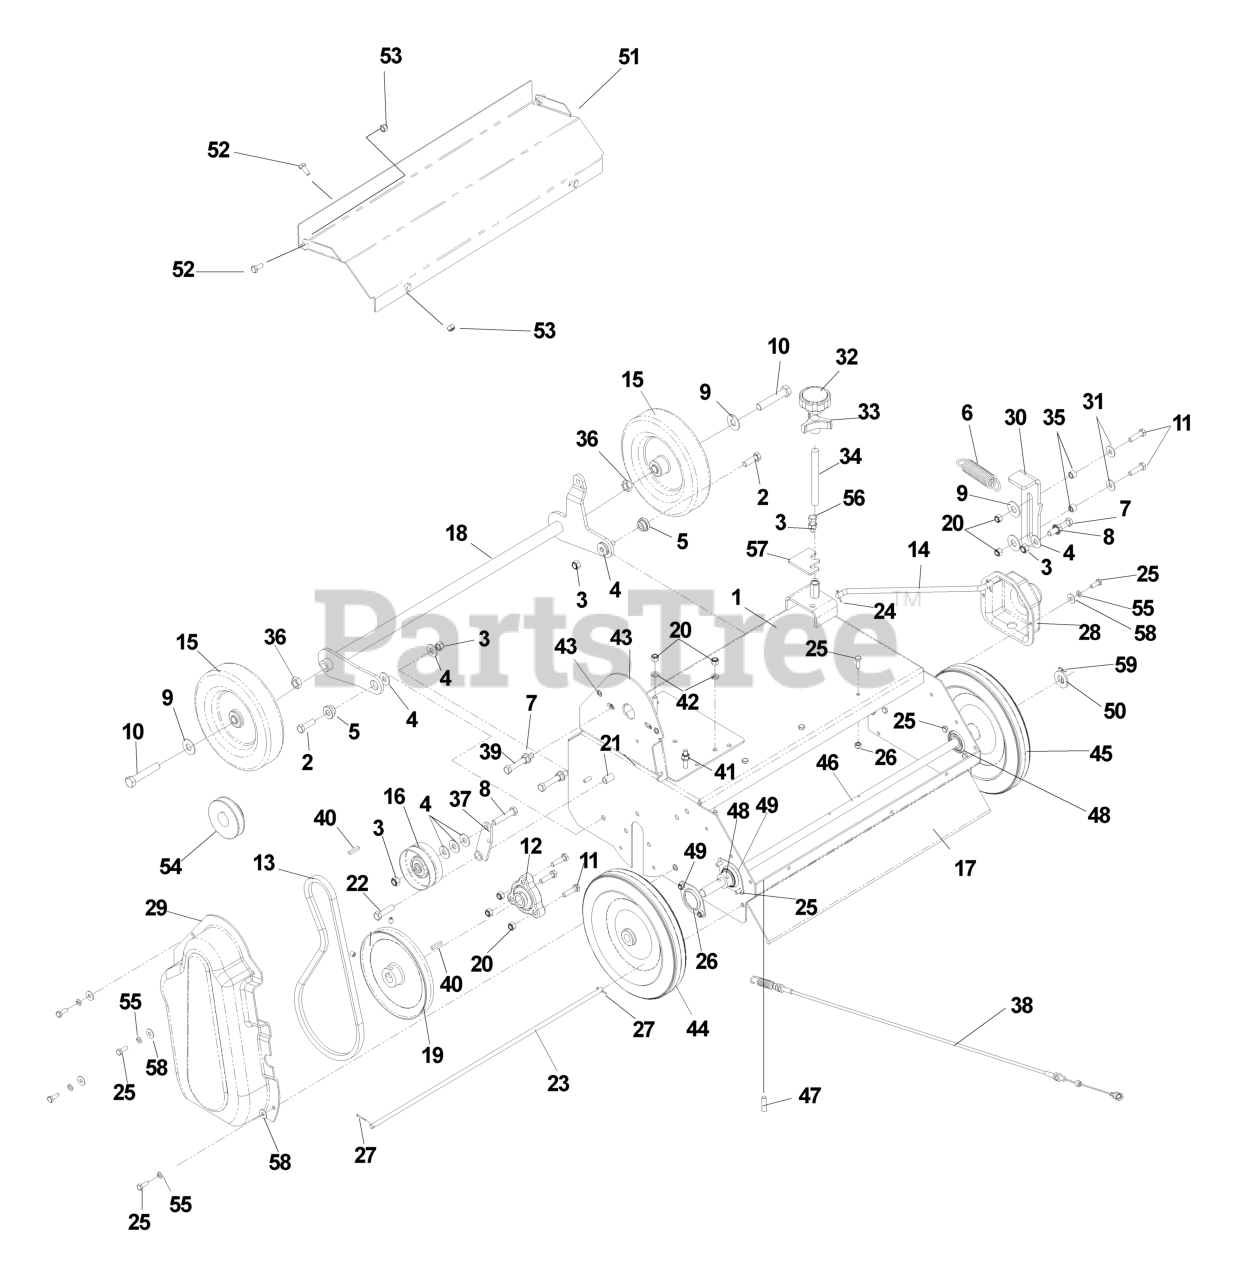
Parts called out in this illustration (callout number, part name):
1	BODY ASSEMBLY
2	HCS 3/8C X 1 1/4 GR5
3	NUT 3/8-16 NYLOC
4	WASHER 3/8 FLAT
5	BUSHING RAKE
7	NUT 3/8C WHIZ
8	HCS 3/8C X 2
9	WASHER 1/2 FLAT
10	HCS 1/2C X 2 3/4
11	HCS 5/16C X 1 1/4
12	BEARING, FLANGED
13	BELT, DRIVE RAKE/SLICER DFS
15	WHEEL 8 X 1 3/4 RAKE
16	PULLEY, IDLER RAKE & ZTR
18	FRONT AXLE
19	PULLEY W/SET SCREW
20	NUT 5/16 NYLOC
21	BEARING, ONLITE RAKE/DT
22	HCS 3/8C X 1 1/2
24	RP_COTTER PIN 1/8 X 3/4
25	HCS 1/4C X 3/4 HCS
26	NUT.1/4-20.HEX.NYLOC.ZD
27	RP_COTTER PIN 1/8 X 3/4
28	SHAFT GUARD
29	BELT GUARD
31	WASHER 5/16 FLAT
32	KNOB, BLACK THERMO PLASTIC
33	KNOB, THREE PRONG
34	THREADED ROD
36	NUT 1/2 HEX JAM
37	IDLER ARM - ORANGE
38	CABLE POWER RAKE
39	HCS 3/8C X 2 1/2
40	KEY
41	HCS 5/16C X 1 3/4
42	WASHER.LOCK.HVY.HLCL.SPR.5/16
43	BACKING PLATE ORANGE
44	WHEEL 10 X 1 3/4
45	WHEEL 10 X 1 3/4
46	AXLE, REAR
47	ROLL PIN 1/4 X 1 1/8
48	BEARING - 5/8" W/COLLAR
49	FLANGE
50	WASHER
51	REAR COVER ORANGE
52	HCS 1/4C X 5/8
53	NUT.1/4-20.HEX.NYLOC.ZD
54	ENGINE PULLEY W/SET SCW
55	LOCKWASHER 1/4"
56	HCS 3/8-16X1.GRD.5.ZD
57	DEPTH SHIM
58	WASHER 1/4 FLAT
59	COTTER PIN
60	KNURLED INSERT
